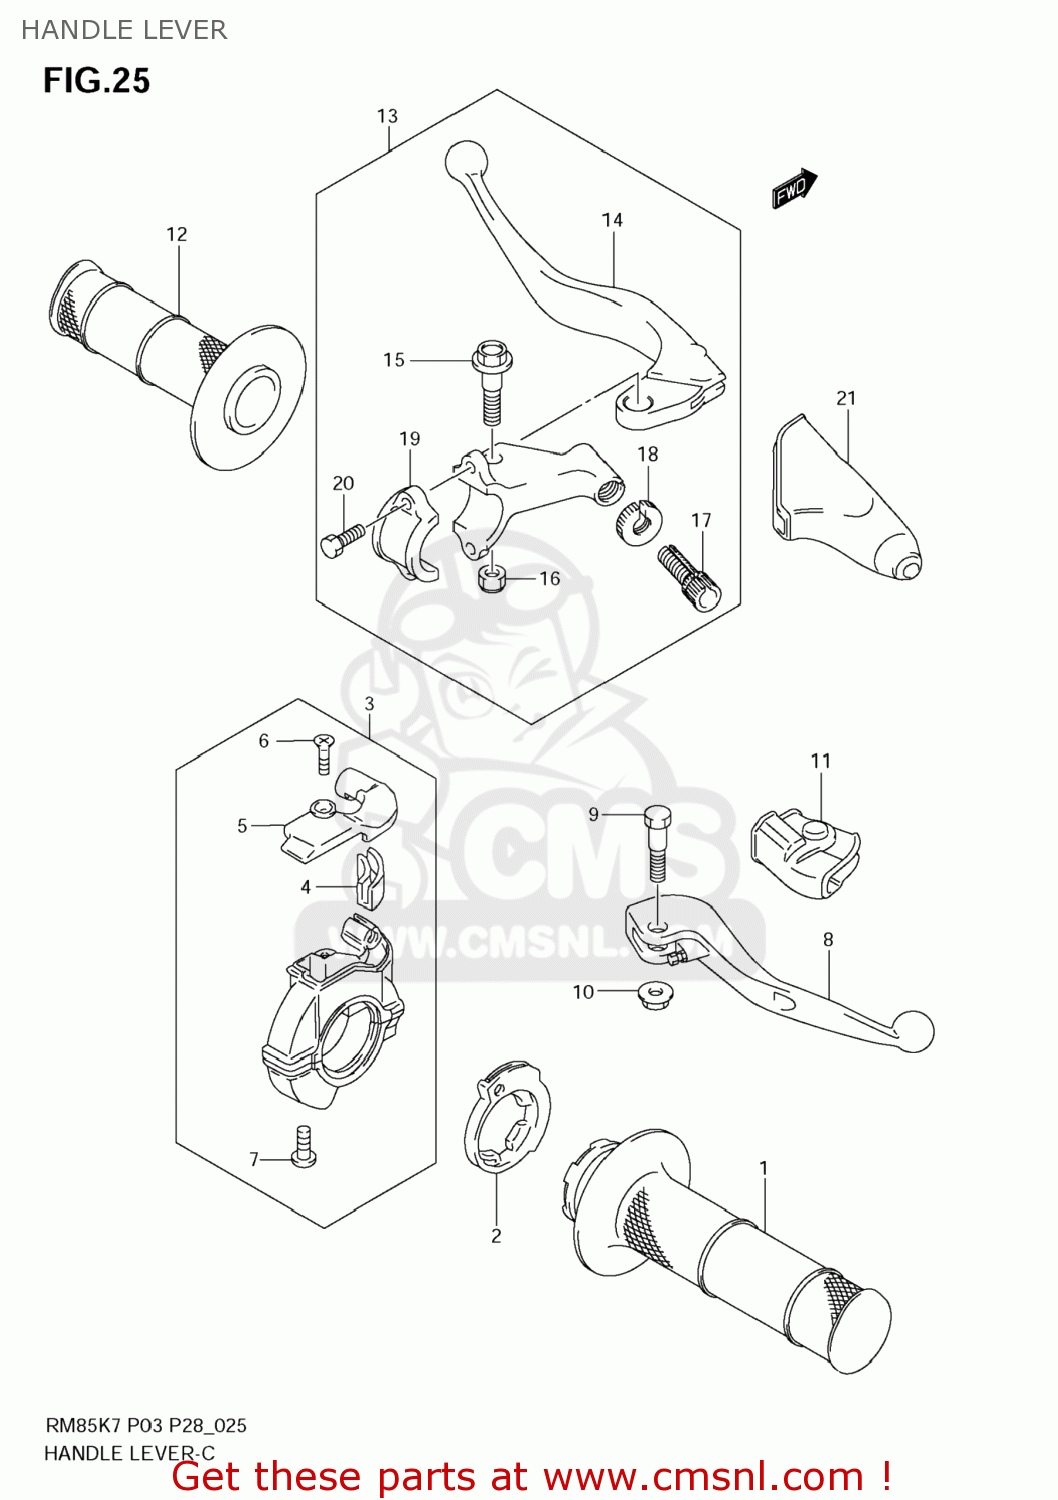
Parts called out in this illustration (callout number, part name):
1	GRIP,THROTTLE
2	ROTER,THROTTLE
3	CASE ASSY,THROTTLE
4	GUIDE PIECE,THROTTLE
5	COVER,THROTTLE CASE
6	SCREW
7	SCREW
8	LEVER ASSY,BRAKE
9	BOLT,BRAKE LEVER
10	NUT
11	COVER,BRAKE LEVER
12	GRIP,L
13	LEVER ASSY,CLUTCH
14	LEVER,CLUTCH
15	BOLT,LEVER
16	NUT
17	ADJUSTER,WIRE
18	NUT,LOCK
19	BRACKET,CLUTCH LEVER HOLDER
20	BOLT
21	COVER,CLUTCH LEVER
